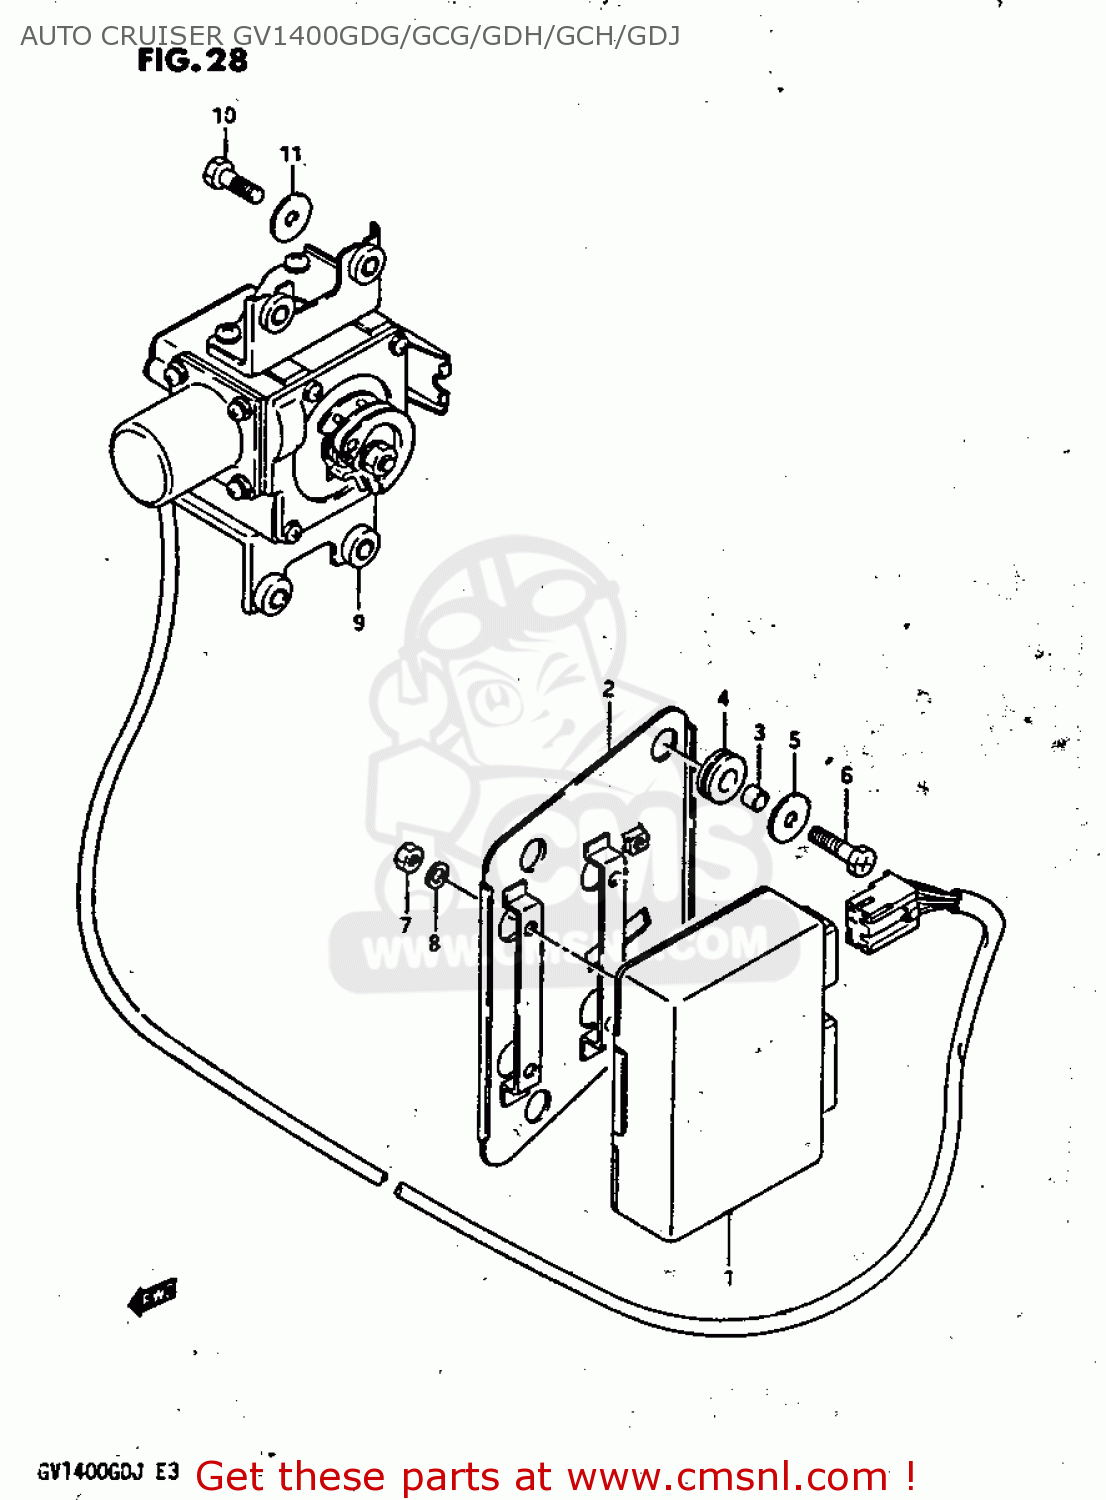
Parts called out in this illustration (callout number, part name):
1	CONTROLLER ASSEMBLY,AUTO CRUISE
2	BRACKET
3	SPACER (7X9X7)
4	CUSHION
5	WASHER
6	SCREW
7	NUT
8	LOCK WASHER
9	ACTUATOR ASSEMBLY,AUTO CRUISE
10	SCREW
11	WASHER
